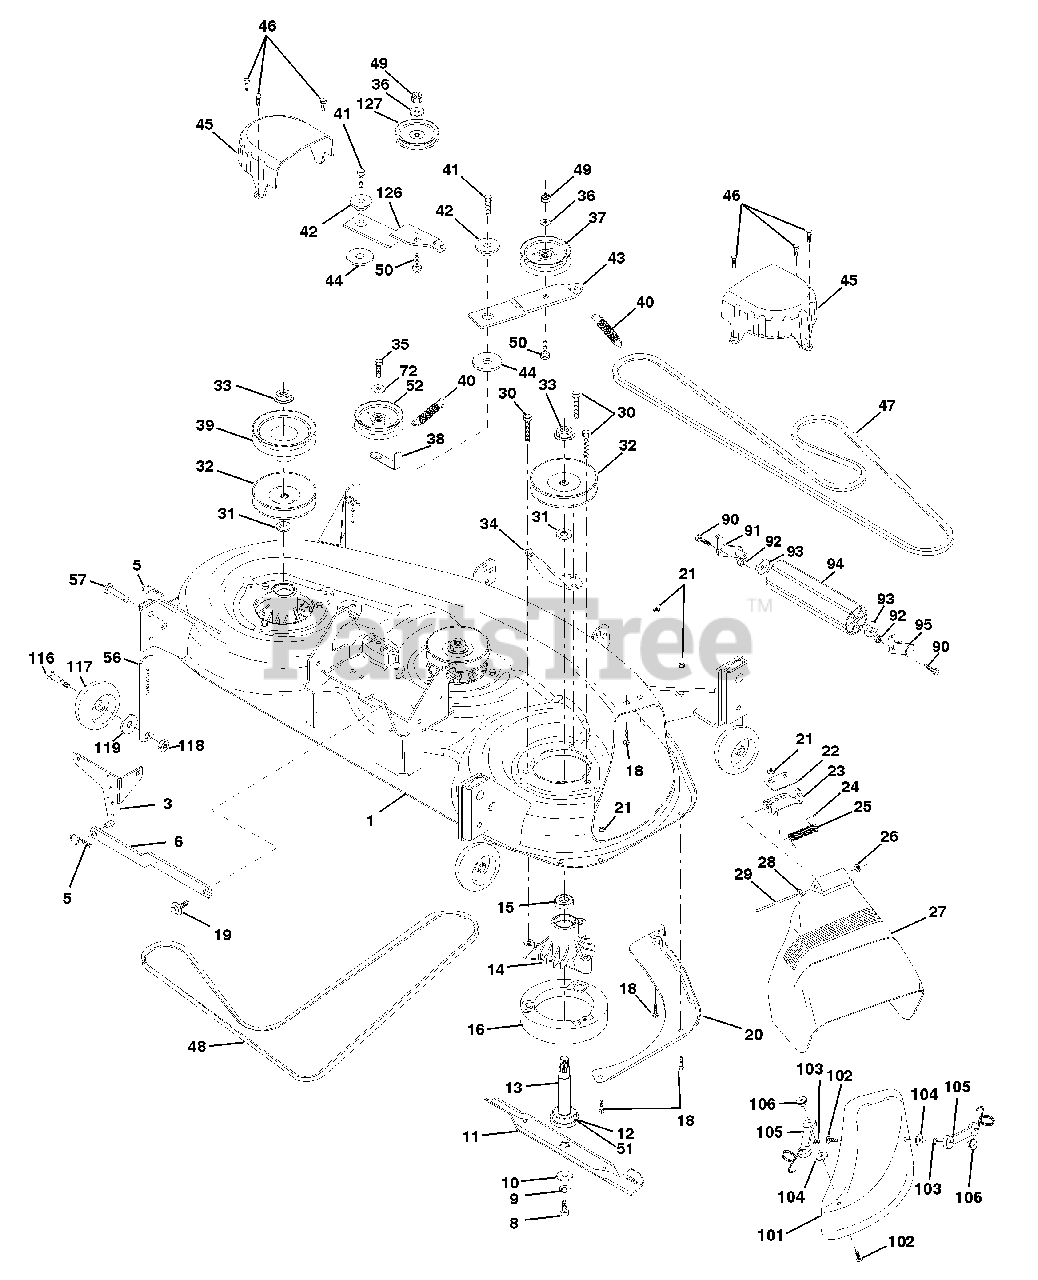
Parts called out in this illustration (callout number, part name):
1	Deck Asm., Mower 46"
3	Bracket Asm., Sway Bar
5	Retainer Spring
6	Arm, Suspension, Rear (Sway Bar)
8	Bolt, Patched 3/8-24 x 1-1/4 Gr. 8
9	Washer, Lock Hvy., Unplated 3/8
10	Washer, Hard Blade, Mower Vented
11	Blade, 46" Mulching
12	Bearing, Ball, Mandrel #6204
13	Shaft Asm. w/Lower Bearing
14	Housing, Mandrel
15	Bearing, Ball, Mandrel
16	Stripper, Mower Round
18	Bolt, Carriage 5/16-18 x 5/8
19	Bolt, Hex Head, Shoulder 5/16-18
20	Baffle, Vortex Mower 46"
21	Nut, Crownlock 5/16-18 UNC
22	Stiffiner, Bracket
23	Bracket, Deflector
24	Cap, Sleeve
25	Spring, Torsion, Deflector
27	Shield, Deflector Mower
28	Washer 11/32 x 5/8 x 16 Ga.
29	Rod, Hinge
30	Screw, Thdroll Washer Hd
31	Washer, Spacer Mower Vented
32	Pulley, Mandrel
33	Nut, Flg. Top Lock Cntr. 9/16
34	Anchor, Spring Deck 46"
35	Screw, Thdroll 3/8-16 x 1-3/4 Tytt
36	Washer 13/32 x 13/16 x 16 Ga.
37	Pulley, Idler, Flat
38	Keeper, Belt, Idler
39	Pulley, Idler, Driven
40	Spring, Secondary 44/46/50 Vent
41	Screw, Thdroll 3/8-16 x 1-1/4 Tytt
42	Spacer, Retainer
43	Arm, Idler Secondary
44	Washer, Hardened
45	Cover, Mandrel Deck
46	Screw, Thdroll. 1/4-20 x 5/8
47	V-Belt, Mower, Secondary
48	V-Belt, Mower, Primary
49	Nut, Crownlock 3/8-16 UNC
50	Bolt, Carriage 3/8-16 x 1-1/2 Gr. 5
51	Washer Felt
52	Pulley Idler Flat 46 PRI drive
56	Bar Pnt Adjusting Wheel Gauge
57	Pin Head Rivet
72	Washer 13/32 x 16 Ga.
90	Bolt Fin Hex 3/8-16 x 1
91	Bracket Asm Noseroller LH
92	Nut Lock Hex W/Ins 3/8-16 UNC
93	Washer 17/32 x 7/8 x 16 Ga.
94	Roller Nose
95	Bracket Asm Noseroller RH
101	Cover, Mulching
102	Screw
103	Washer, Lock #10
105	Latch Asm. Mulch/Bagger
106	Nut, Weld
116	Bolt, Shoulder
117	Gauge Wheel, Wide
118	Nut, Centerlock 3/8-16 UNC
119	Washer 3/8 x 7/8 x 14 Ga.
126	Arm, Idler, Primary Deck 46"
127	Pulley, Idler, V-Groove Dim. 4.25
128	Washer 13/32 x 1-3/8 x 3 Ga.
